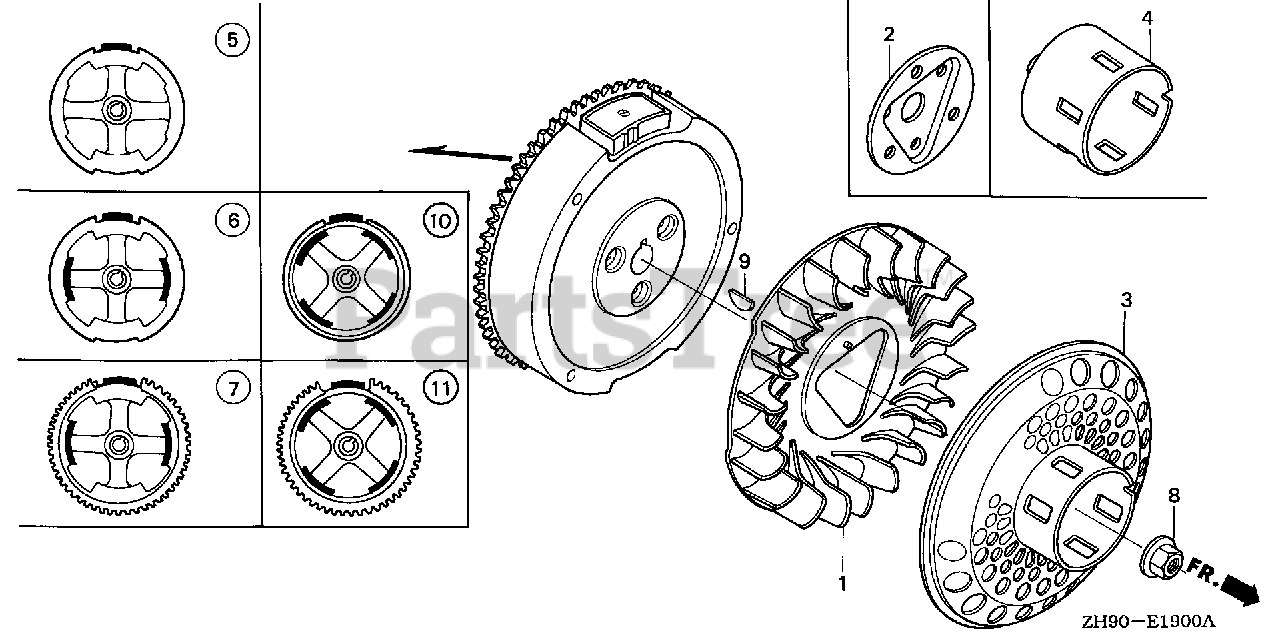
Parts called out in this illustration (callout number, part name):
1	FAN, COOLING
3	PULLEY, STARTER (SCREEN GRID)
8	NUT, SPECIAL (16MM) (1)
9	KEY, SPECIAL WOODRUFF (25X18)
11	FLYWHEEL (4POLE)
